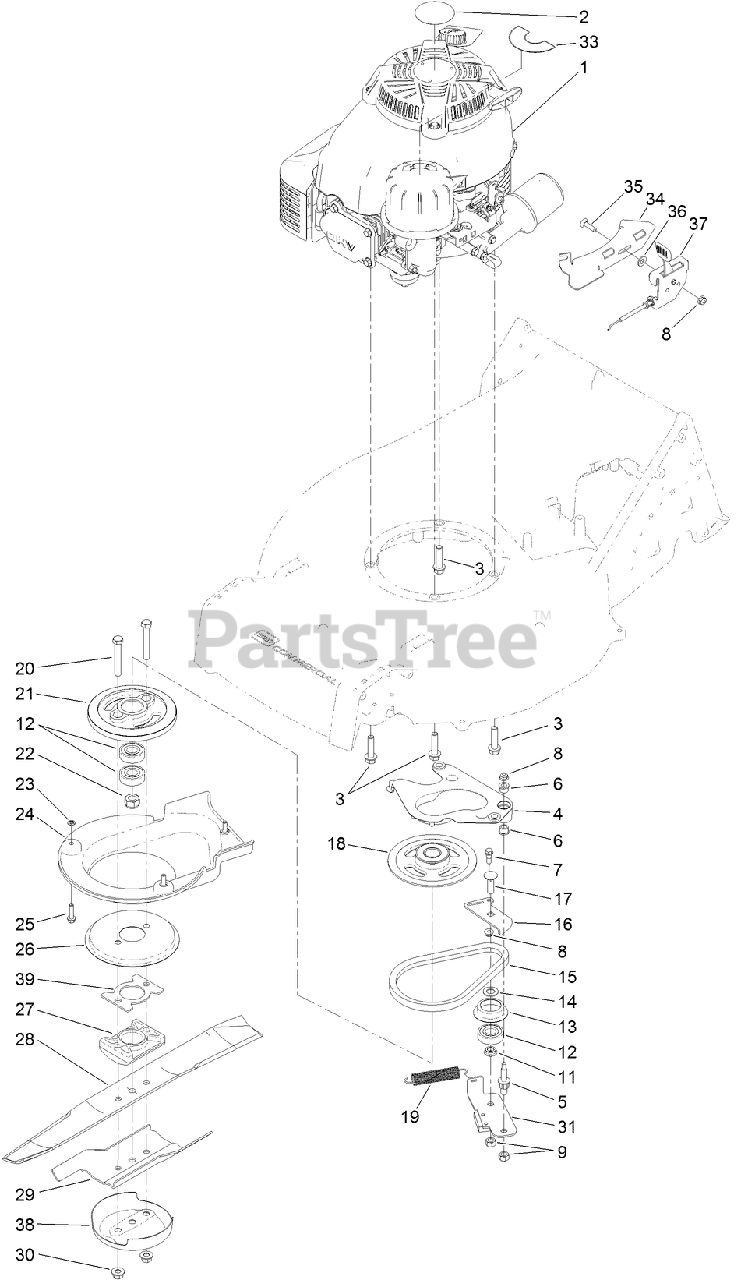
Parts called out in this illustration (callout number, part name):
1	ENGINE-KAWASAKI, FJ180V
3	SCREW-HWH
4	PLATE-ANCHOR
5	BOLT-SHOULDER
6	BUSHING-FLANGE
7	BOLT-SHOULDER
8	NUT-HF
9	NUT-HEX
11	SPACER-BEARING
13	RETAINER-BELT
14	SPACER
15	BELT
16	PLATE-GUIDE, BBC
17	BOLT-CARR
18	PULLEY
19	SPRING-TENSION, BRAKE
20	SCREW-HH
22	NUT-HEX
23	NUT-RETAINER
25	SCREW-HWHTF
26	DISC
27	SUPPORT-BLADE
29	ACCELERATOR-BLADE
30	NUT-FLANGE, LOCK
31	PLATE-BRAKE
34	BRACKET-MOUNT, THROTTLE
35	SCREW-CARR
36	WASHER-PLAIN
37	THROTTLE
38	CUP-ANTI SCALP
39	SPACER-DRIVER, BLADE
